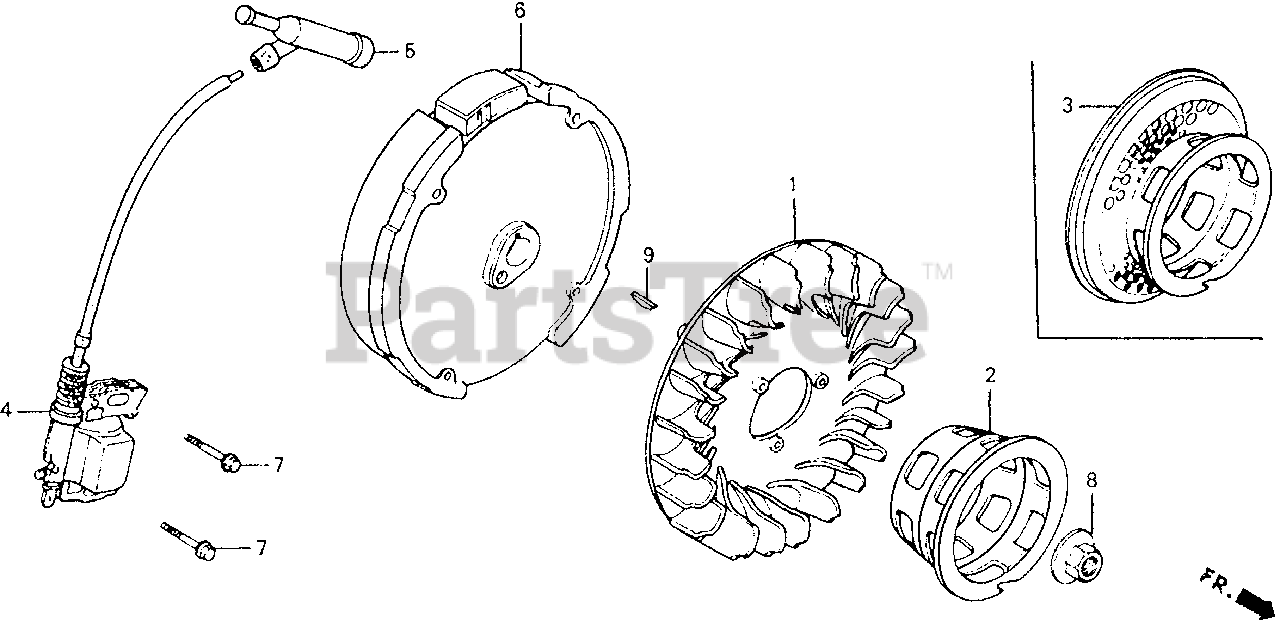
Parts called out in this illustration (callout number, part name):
1	FAN, COOLING
2	PULLEY, STARTER
4	COIL ASSY., IGNITION
5	CAP ASSY., NOISE SUPPRESSOR
6	FLYWHEEL
7	BOLT, FLANGE (6X25)
8	NUT, SPECIAL (14MM)
9	KEY, SPECIAL WOODRUFF (25X18)
